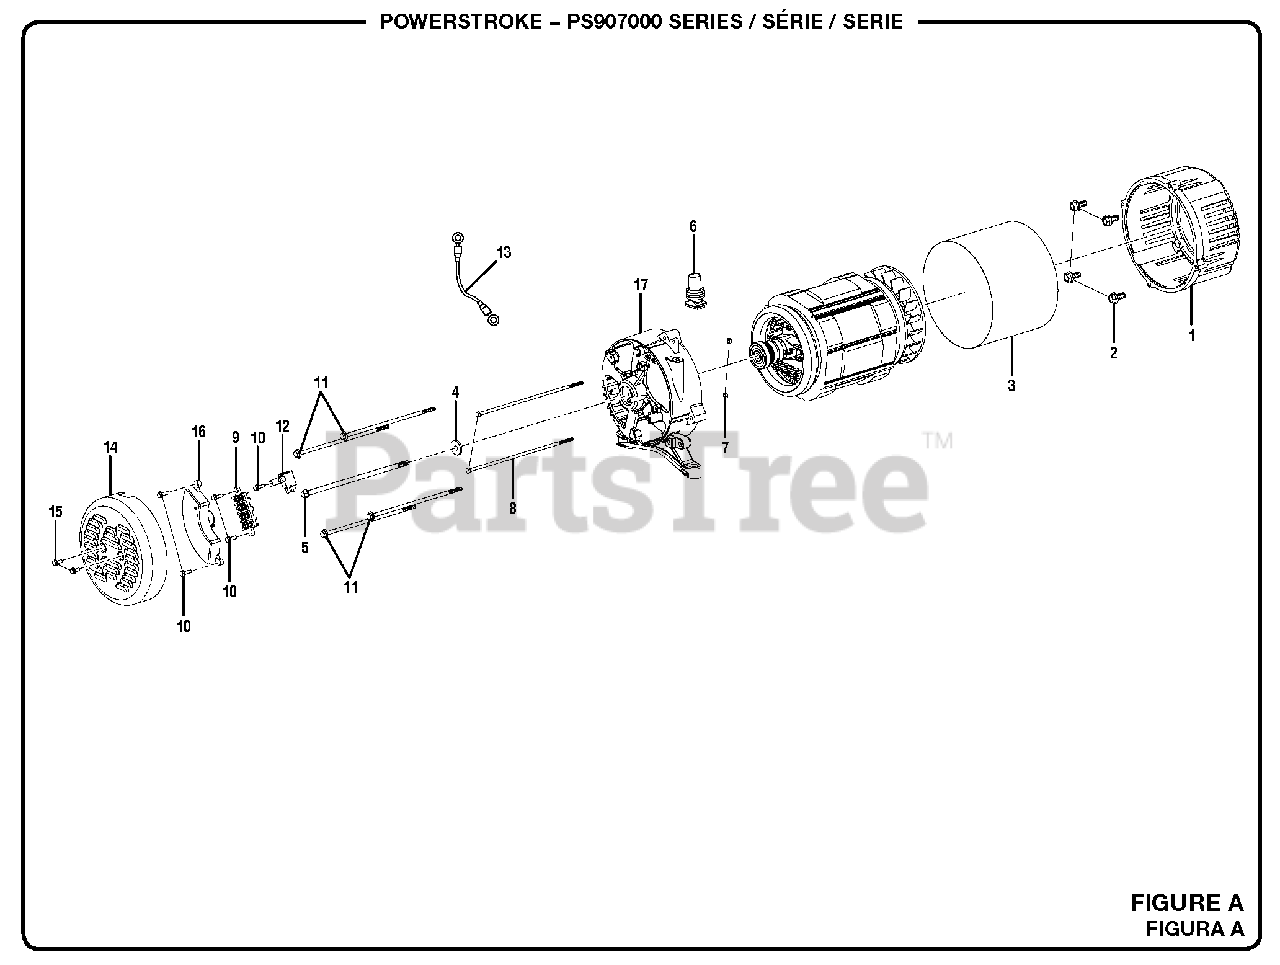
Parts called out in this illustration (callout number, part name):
1	Adaptor Housing
2	Bolt (3/8-16 x 1- 1/4 in.)
3	Generator Head Cover
4	Washer (Rotor)
5	Rotor Bolt
6	Rubber Boot
7	Hex Nut (M5)
8	Bolt (M5)
9	Terminal Block
10	Bolt (M5 x 16 mm)
11	Bolt (Stator)
12	Brush Assembly
13	Bonding Wire
14	Brush Cover
15	Bolt (M5 x 12 mm)
16	Automatic Voltage Regulator
17	Bearing Housing
